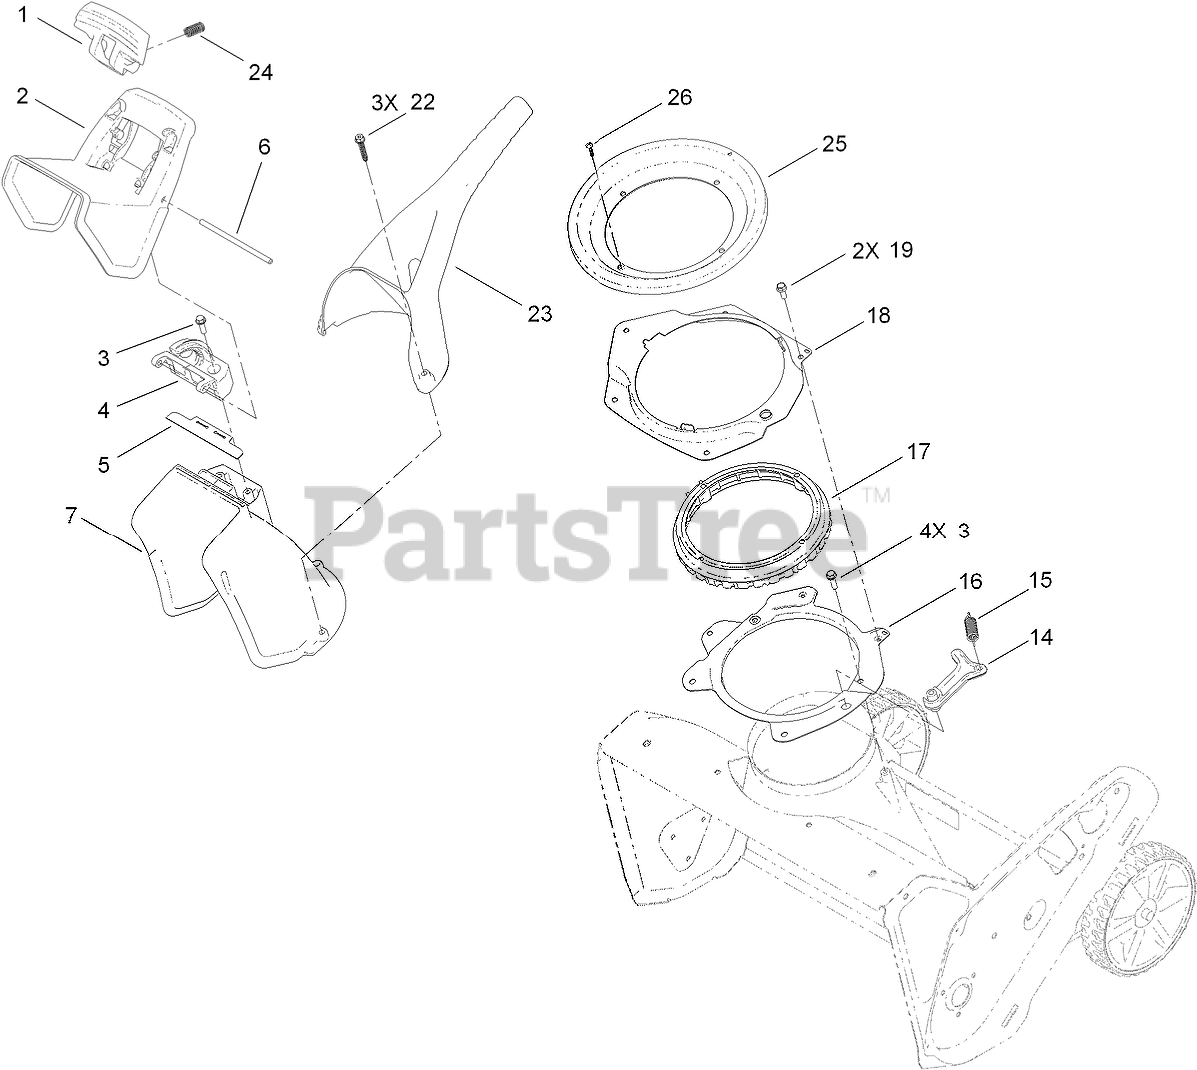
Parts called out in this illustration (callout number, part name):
1	TRIGGER-DEFLECTOR
2	DEFLECTOR-CHUTE, CE
3	SCREW-HWH
4	HINGE-RATCHET, DEFLECTOR
5	SEAL-DEFLECTOR
6	PIN-HINGE, DEFLECTOR
14	PAWL-DETENT
15	SPRING-EXTENSION
16	RING-SUPPORT, CHUTE
17	RING-CHUTE, DETENT
18	RETAINER-RING, CHUTE
19	SCREW-HWH
22	SCREW-HWH, PLASTITE
23	HANDLE-CHUTE
24	SPRING-COMPRESSION
25	SEAL-RING, CHUTE
26	SCREW-PPH
